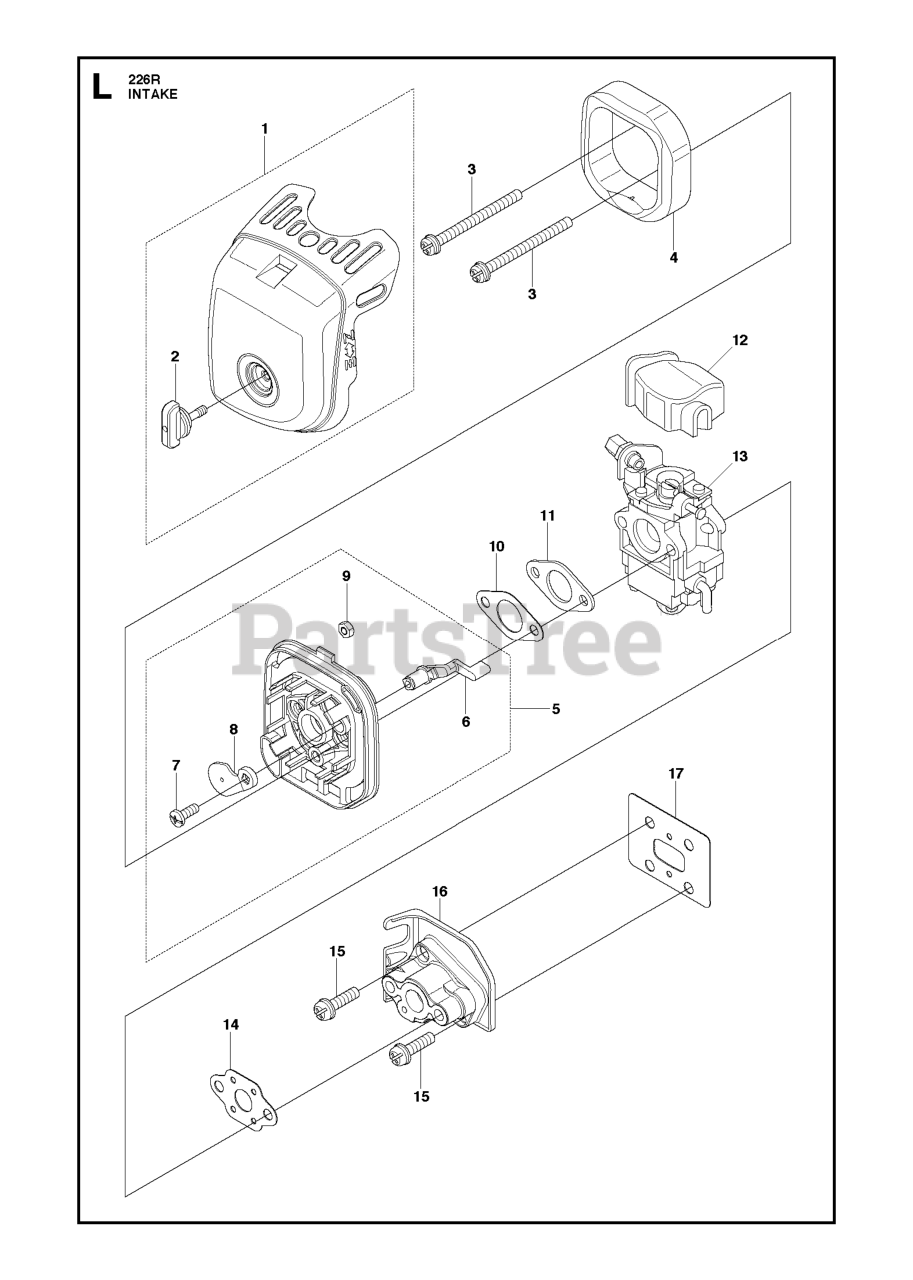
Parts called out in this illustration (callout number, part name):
7	SCREW
8	PLATE.CHOKE
13	CARBURETOR-A
